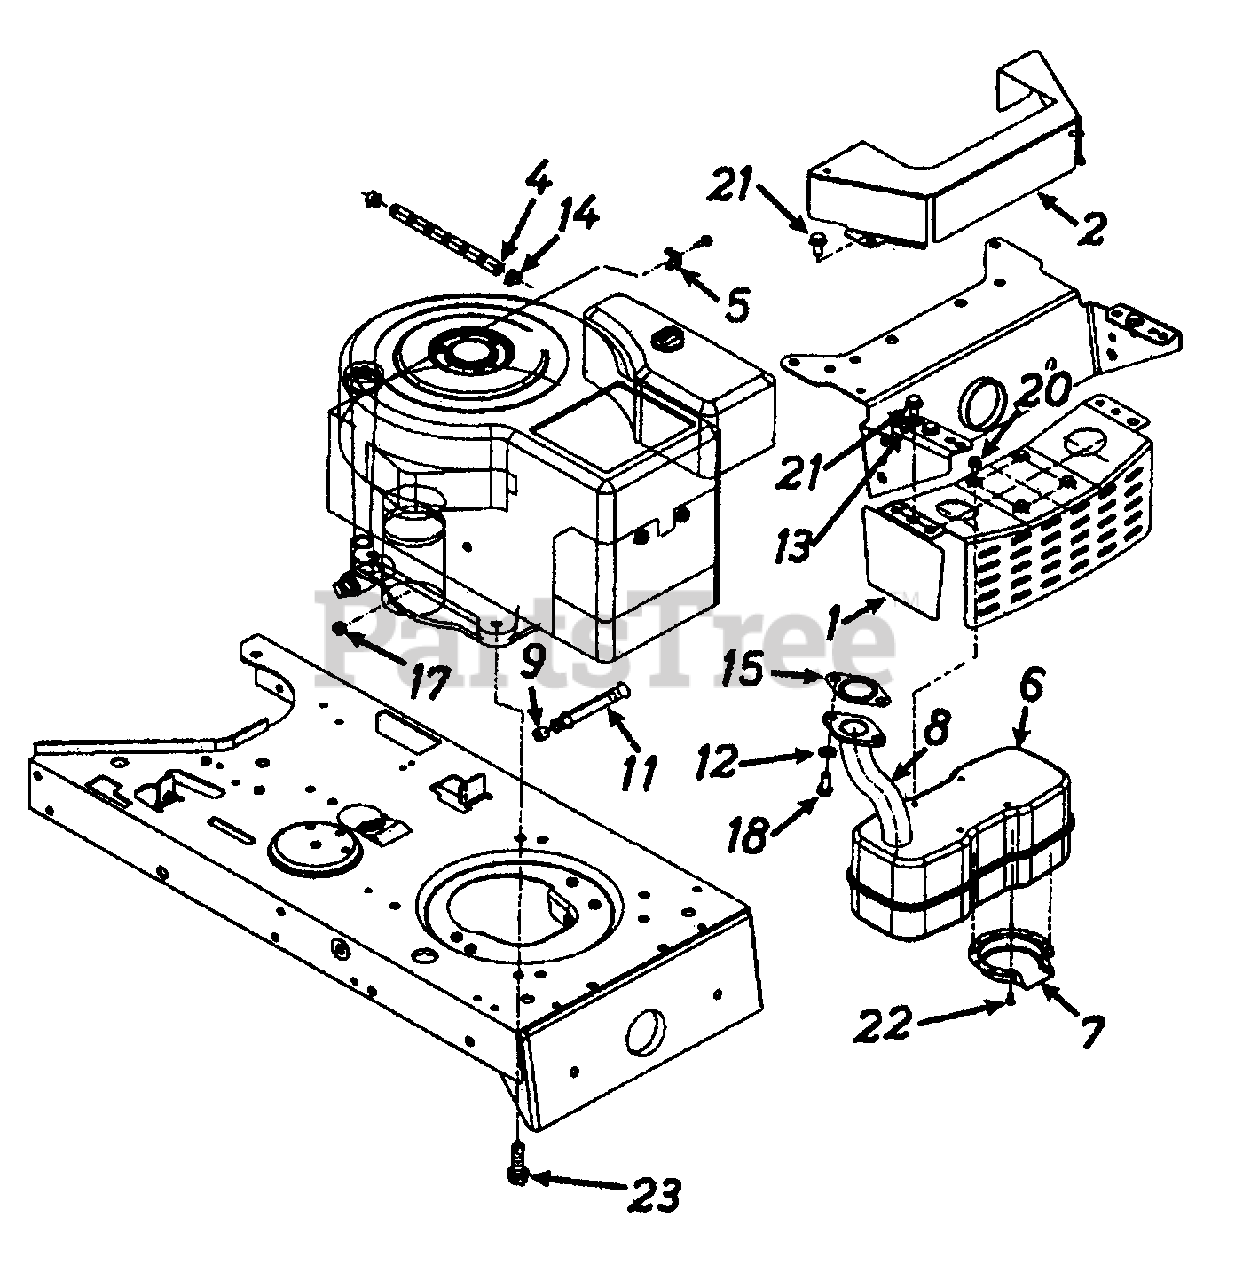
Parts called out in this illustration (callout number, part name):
1	Heat Shield Bracket
4	Fuel Line
5	Casing Clamp
6	Muffler
7	Muffler Deflector
8	Exhaust Pipe
9	Hex Pipe Plug
11	Pipe 3/8 NPT x 3.8" Lg.
12	L-Wash. 5/16" I.D.
13	Clamp
14	Hose Clamp
15	Exhaust Gasket
17	Hex Sems Nut 1/4-20 Thd.
18	Socket Hd. Bolt 5/16-18 x .62" Lg.
20	Hex Wash. Hd. TT-Scr. 1/4-20 x .5" Lg.
21	Hex Wash. Hd. TT-Scr. 5/16-18 x .62" Lg.
22	Hex Bolt #8-32 x .38" Lg.
23	Hex Wash. Hd. TT-Scr. 3/8-16 x 1.25" Lg.
